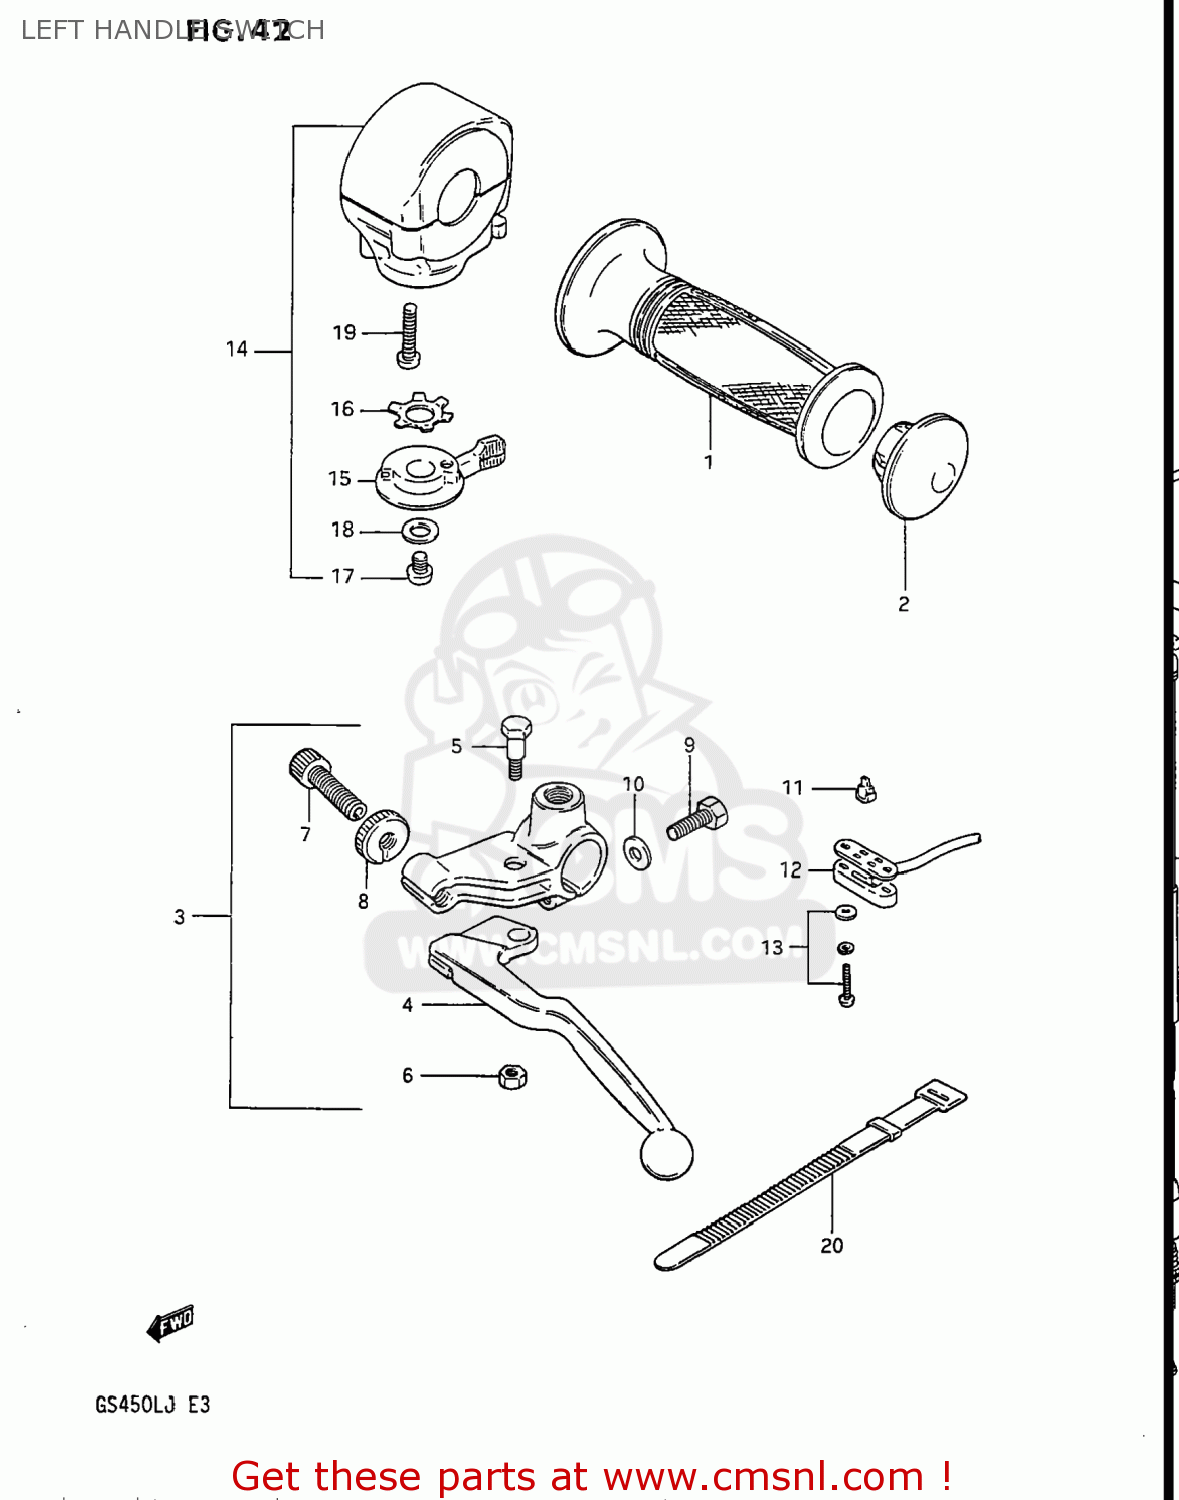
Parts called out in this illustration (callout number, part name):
1	GRIP
2	CAP,GRIP END
3	LEVER ASSY,CLUTCH
4	LEVER,CLUTCH
5	BOLT,LEVER PIVOT
6	NUT
7	ADJUSTER,CABLE
8	NUT,CABLE ADJUSTER LOCK
9	BOLT
10	WASHER
11	CONTACT,SWITCH
12	COVER,FR BK TERMINAL BASE
13	SCREW
14	SWITCH ASSEMBLY,HANDLE,LEFT
15	LEVER,STARTER
16	WASHER
17	SCREW
18	WASHER 6MM
19	SCREW
20	CLAMP(L:120)
